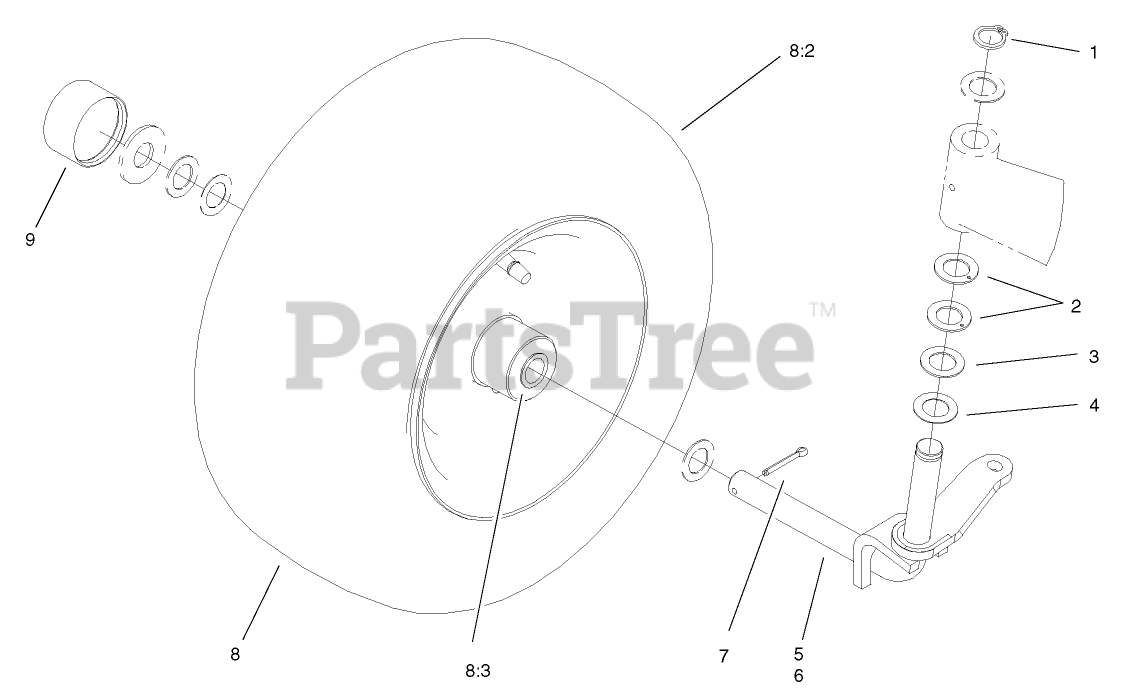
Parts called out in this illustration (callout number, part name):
1	RING-RETAINING
2	WASHER-SLIP
3	WASHER
4	Race Thrust
5	RH SPINDLE ASM
6	LH SPINDLE ASM
7	PIN-COTTER
8	WHEEL & TIRE ASM
8:2	Tire (16 x 6.5-8) 2-Ply -2 Wheel Axel
8:3	BEARING-RADIAL FLNGE
9	CAP-HUB
